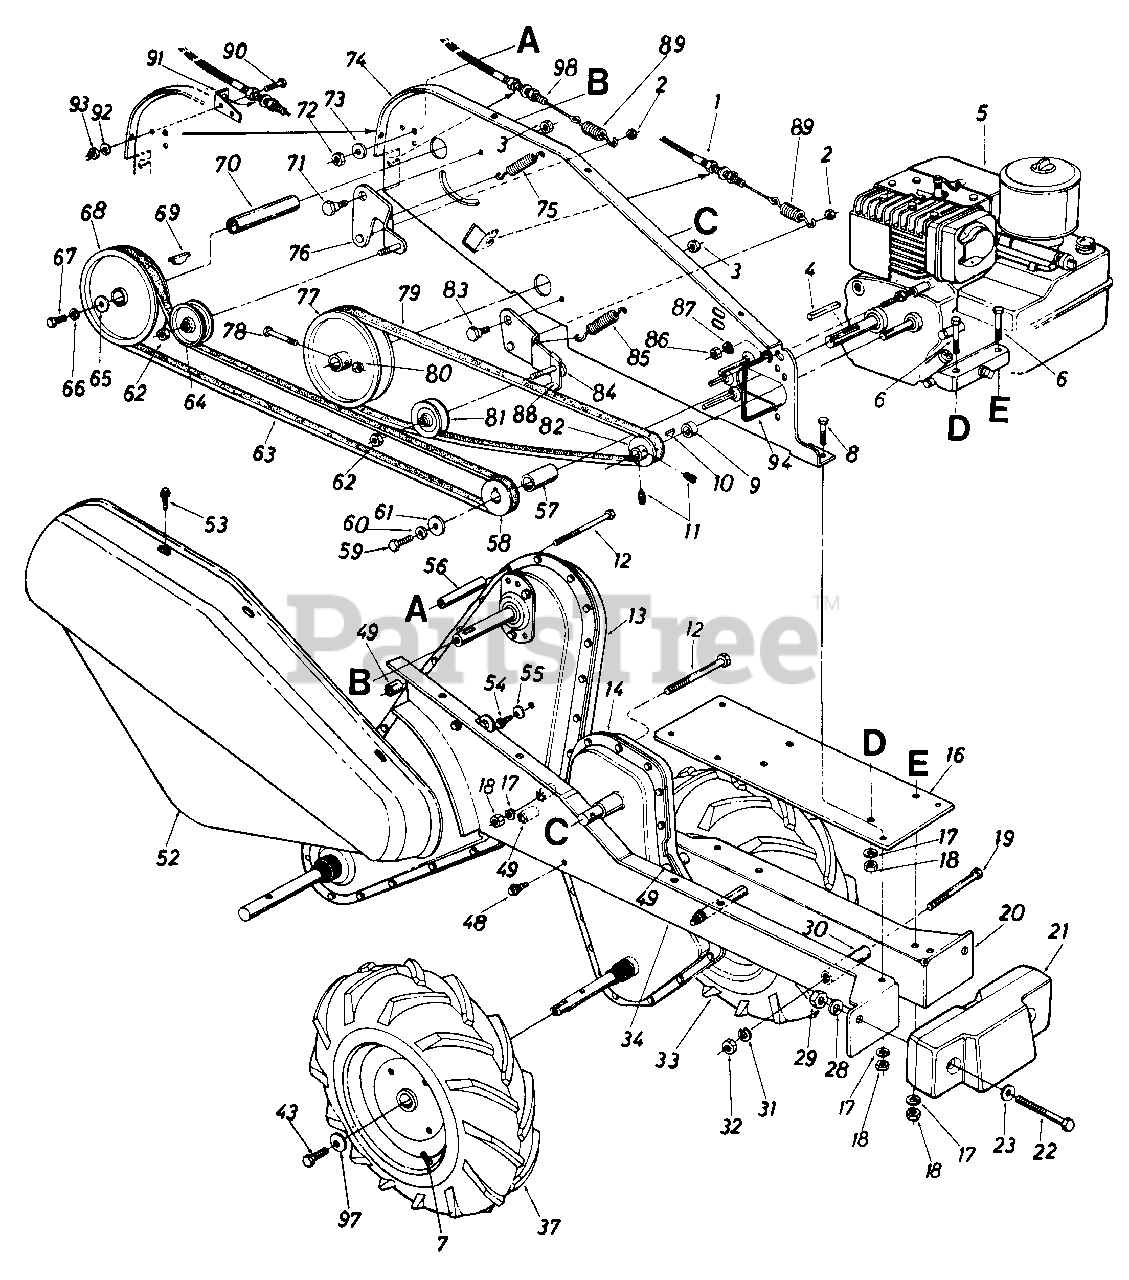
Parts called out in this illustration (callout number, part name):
1	Clutch Control Cable
2	Hex Cent. L-Nut 1/4-20 Thd.
3	Hex Cent. L-Nut 3/8-16 Thd.
4	Sq. Key 3/16" Dia. x .75
5	Engine
6	Hex Bolt 5/16-18 x 1.50" Lg.
7	Air Valve
8	Hex Bolt 5/16-18 x .75" Lg.
9	Spacer .51" I.D. x 3/4" O.D. x .39' Lg.
10	Hi-Pro Key #5 Woodruff
11	Set Scr. 1/4-28 x .25" Lg.
12	Hex Bolt 5/16-18 x 3.0" Lg.
18	Hex Nut 5/16-18 Thd.
19	Hex Bolt 3/8-24 x 3.0" Lg.
22	Hex Bolt 1/2-13 x 4.0" Lg.
23	Fl-Wash. 1/2" I.D. x 1.0" O.D.
28	L-Wash. 1/2" I.D.
29	Hex Nut 1/2-13 Thd.
30	Spacer 3/8" I.D. x 618n O.D. x 2.18" Lg.
31	L-Wash. 3/8" I.D.
32	Hex Nut 3/8-24 Thd.
33	Comp. Wheel Ass'y.-L.H.
48	Hex Wash. Self-Tap Scr. 5/16-24 x 50n Lg.
49	Spacer 5/16" I.D. x 16 Ga. x.96" Lg.
54	Hex Wash. S-Tap Scr. 1/4-20 x 3/8" Lg.
55	Bell-Wash. 1/4" I.D.
56	Spacer 3/8" I.D. x 1/2" O.D. x 2.0" Lg.
57	Spacer 3/4" I.D. x 1.12" O.D. x 1.56" Lg.
58	1/2" "V"-4L Pulley 3/4" I.D. x 2.59" O.D.
59	Hex Bolt 5/16-24 x 1.0" Lg.
60	L-Wash. 5/16" I.D.
61	Fl-Wash. 5/16" I.D. x 1.25" O.D.
62	Hex L-Nut 3/8-24 Thd.
63	"V"-Belt
64	Fl-Idler Pulley 3.75" O.D. x 3/8" I.D.
65	Fl-Wash. .25" I.D. x .93" O.D. x .120
66	L-Wash. 1/4" I.D.
67	Hex Bolt 1/4-28 x .75" Lg.
68	Split Pulley 6" Dia. x 5/8" I.D.
69	Hi-Pro Key
70	Spacer
71	Shld. Bolt 1/2" Dia. x .210" Lg.
72	Hex Nut 5/16-18 Thd.
73	L-Wash. 5/16" I.D.
74	Side Plate Ass'y.
75	Ext. Spring 50" O.D. x 1 55" Lg.
76	Idler Bracket Ass'y.-Tines
77	Pulley 6n Dia. x 5/8n I.D.
78	Hex Bolt 1/4-28 x 1.50" Lg.
79	"V"-Belt
80	Hex Cent. L-Nut 1/4-28 Thd.
81	"V"-Idler Pulley 2-5/8" O.D.
82	1/2" "V"-Pulley 21/4" O.D. x 50n I.D.
83	Shld. Bolt 1/2" Dia. x .160" Lg.
84	Idler Bracket Ass'y-Wheels
85	Ext. Spring .50" O.D. x 1.55" Lg.
86	Hex Nut 1/4 -20 Thd .
87	Bell-Wash. 1/4" I.D.
88	Belt Keeper Ass'y.
89	Ext. Spring
90	Hex Bolt 5/16-18 x 75n*
91	Clutch Cable Brkt.
92	Lock Washer 5/16" I.D.
93	Hex Nut 5/16-18 Thd.
94	Belt Keeper
97	Bell-Wash. 5/16" I.D.
98	Clutch Control Cable
